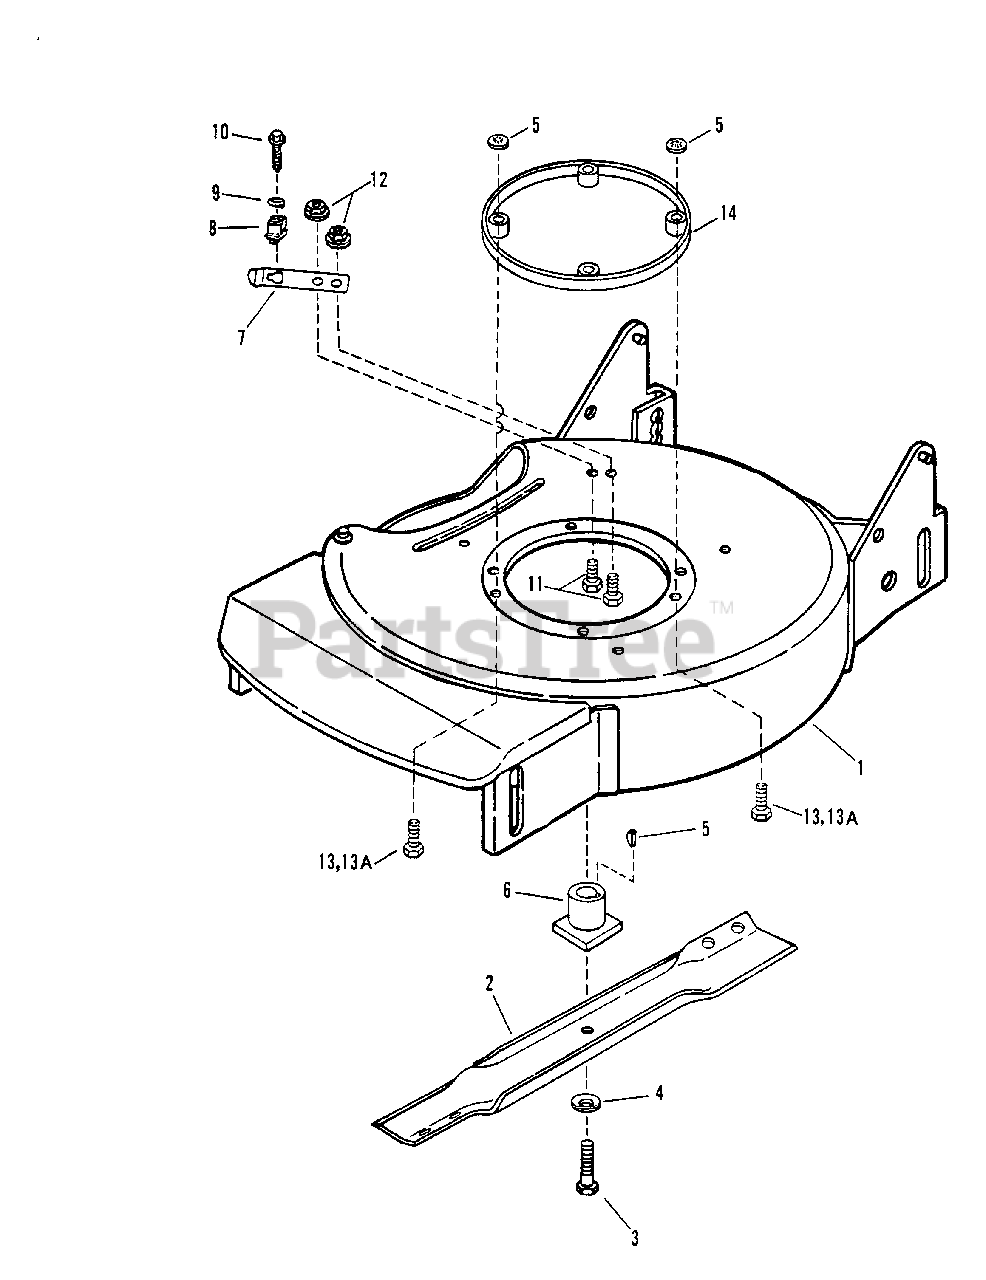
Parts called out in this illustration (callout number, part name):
1	DECK, Mower
2	BLADE, Cutter
3	SCREW, 3/8-24 x 2" Hex Head Cap (Gr. 5)
4	WASHER, Cone
5	RETAINER, 3/8 Bolt
6	HUB, Drive Blade
7	SPRING, Interlock
8	INSULATOR, Interlock
9	WASHER, #8 Tab
10	SCREW, #8-18 x 3/4" Self-Tapping
11	SCREW, 1/4-20 x 3/4" Hex Flange Lock
12	NUT, 1/4-20 Hex Flange
13	SCREW, 3/8-16 x 1" Self-Tapping
13A	SCREW, 3/8-16 x 2" Self-Tapping
14	RING, Spacer Structure
